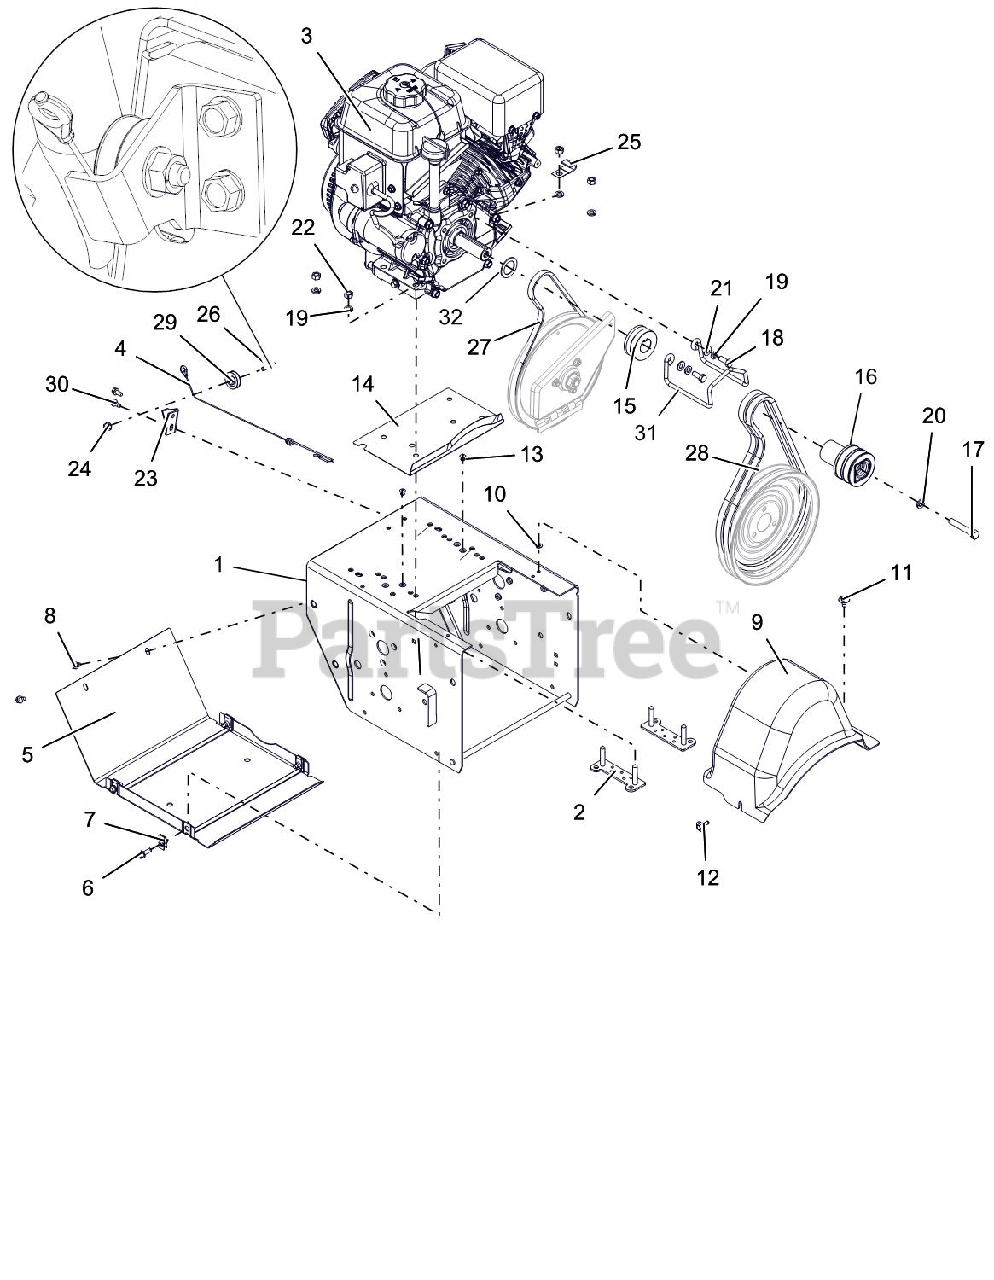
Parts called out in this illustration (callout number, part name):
1	FRAME, MAIN-DELUXE(WELDMENT)
2	STRAP, BOLT - SMALL ENGINE
3	ENGINE, AX254 GEN 2 120V/60W
4	CABLE, LOWER TRACTION,SS & PRO
5	COVER, BOTTOM
6	BLT-HEX .25-20X.75 HWH YZ GR5
7	NUT-RTNR .25-20X.56
8	SCR-TAP .25-20X.50 HWH TR YWZ
9	COVER, BELT-SMALL
10	NUT-PUSH .25X.50 O.D.
11	SCR-TAP .25-20X.50 LGHWH TR YZ
12	SCR-TAP .25-20X.5 CAPTIVE
13	RVT-POP .187 YZ
14	BAFFLE, WATER-SMALL
15	SHEAVE, DRIVE
16	SHEAVE, ATTACHMENT 2-GRV
17	BLT-HEX .38-24X2.25 YWZC GR5
18	BLT-HEX .31-24X.75 YWZC GR5
19	WSHR-LK .312X.097 HVY YWZC
20	@WSHR-LK .38X.094 REG YWZC
21	@WSHR-FL-STL.344X.688X.065YWZC
22	@NUT-HEX .31-18 YWZC
23	BRACKET, CABLE PULLEY
24	@NUT-LK-TOP-FLG .25-20 YWZC
25	J-CLAMP
26	BOLT, SHLDR-.375X.375X.25-20
27	V-BELT, 3L-WRAPPED
28	V-BELT, HA-RAW EDGE (SET)
29	PULLEY, CABLE
30	SCR-TAP .25-20X.50 HWH TR YWZ
31	FINGER, BELT
32	WSHR-FL-STL 1.010X1.505X.062YZ
